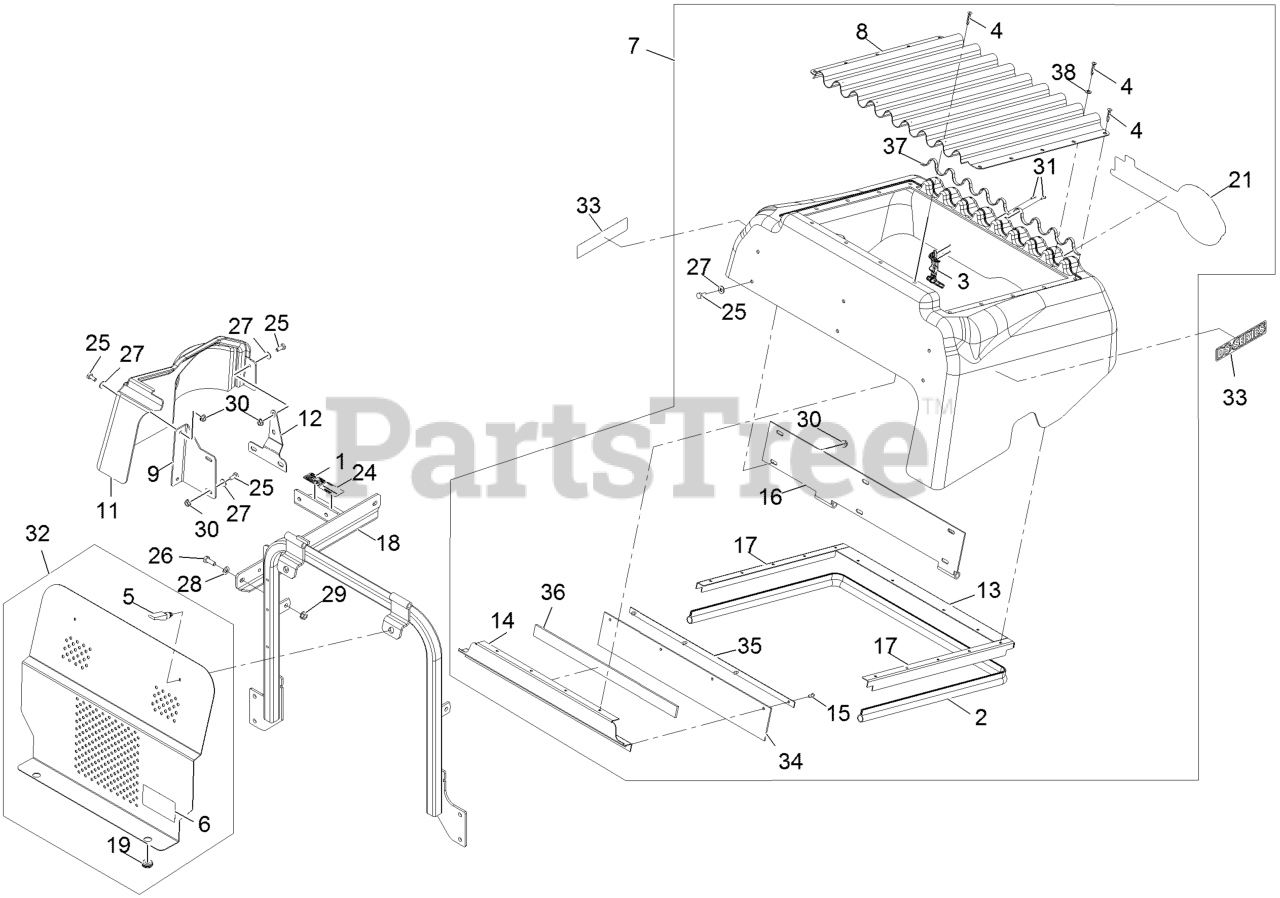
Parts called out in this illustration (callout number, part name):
1	DECAL-CAUTION
2	Seal-Trim 54.6
3	LATCH-RUBBER
5	LATCH-SWELL
6	DECAL,HYDRO BELT ROUTING
7	HOOD ASM, D902
8	SCREEN, RADIATOR
9	BRACKET,FRONT COVER
11	PANEL, SIDE
12	BRACKET,REAR COVER
13	MOUNT-SEAL REAR
14	MOUNT-SEAL FRONT
15	Pop Rivet.187X.188/.25Al(Ad64Abs)
16	WLD, HINGE
17	MOUNT-SEAL SIDE
18	ASM,AIR CLNR BRKT W/DECAL
19	GROMMET
21	DECAL,EXMARK
24	DECAL-CAUTION
25	SCREW-HH
26	SCREW-HH
27	WASHER-FLAT
28	WASHER-PLAIN
32	ASM,AIR DEFLECTOR W/ DECA
33	DECAL, DS SERIES
34	SEAL-RADIATOR HOOD
35	PLATE-SEAL BACKUP
36	SEAL-FRONT SCREEN
37	SEAL-REAR SCREEN
38	WASHER-FLAT
